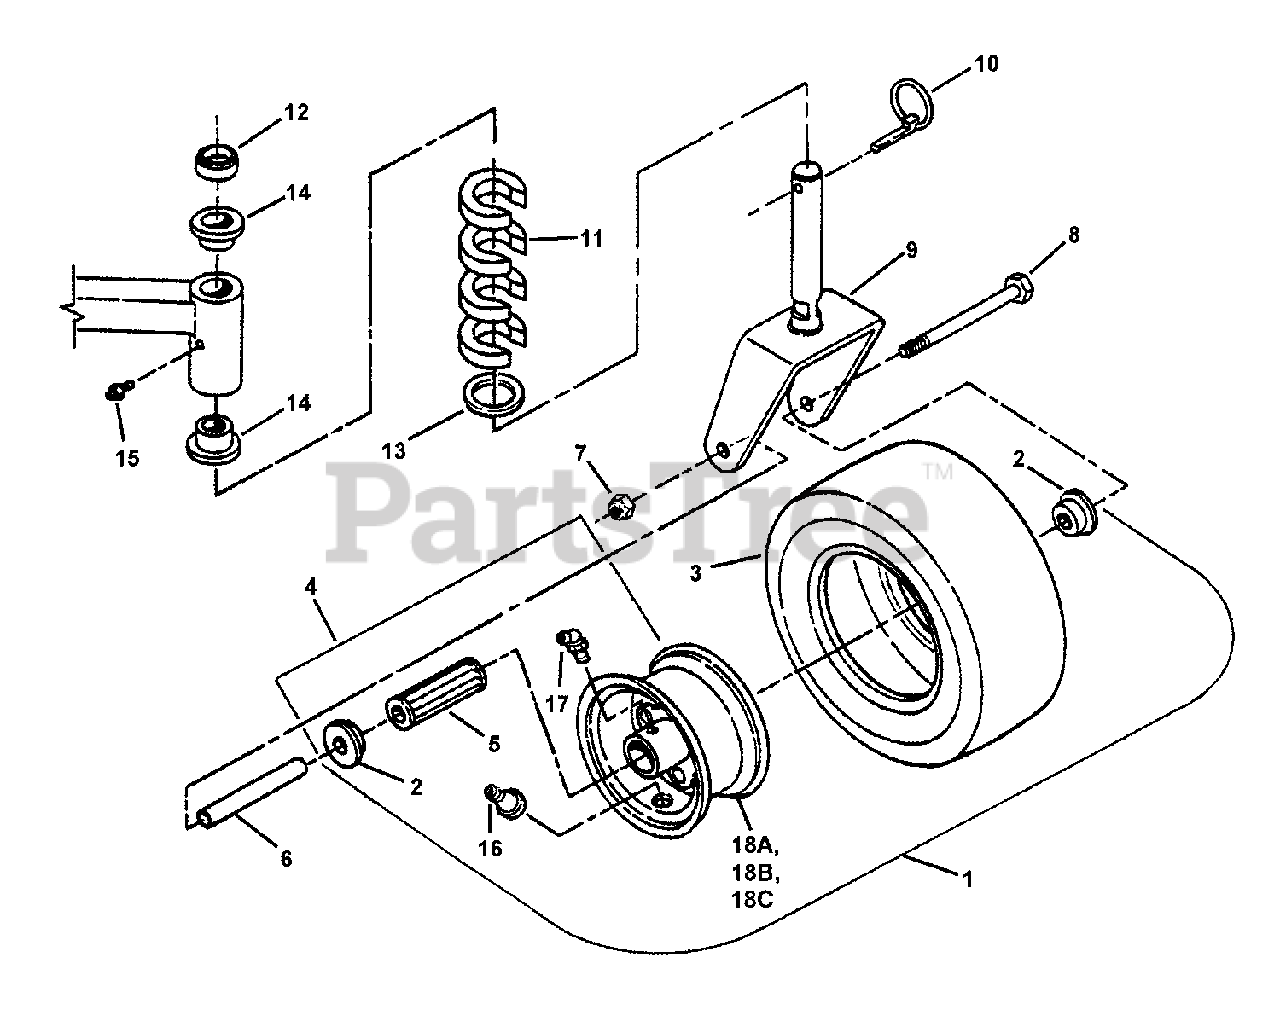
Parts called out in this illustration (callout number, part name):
1	ASSEMBLY, Wheel & Tire- Gray
2	RETAINER, Flanged
3	TIRE, 9 x 3.50-4, 4 Ply Smooth Tread
4	ASSEMBLY, Wheel
5	BEARING, Roller
6	SLEEVE, Axle
7	NUT, 1/2-13 HEX NYLON LOCK
8	BOLT, 1/2-13 X 5-1/2" GD5 YZ
9	WELDMENT, Caster
10	PIN, Lynch 7/16" Heavy Duty
11	SPACER, Caster
12	SPACER, Powdered Metal
13	BUSHING, 1"
14	BUSHING, Caster
15	FITTING, 1/4-28 Straight Lube
16	VALVE STEM
17	FITTING, 1/4-28 45 Degree Lube
18A	RIM, One Piece Steel, Gray
18B	RIM, One Piece Steel, White
18C	RIM, One Piece Steel 4" x 1-3/8" Bore
